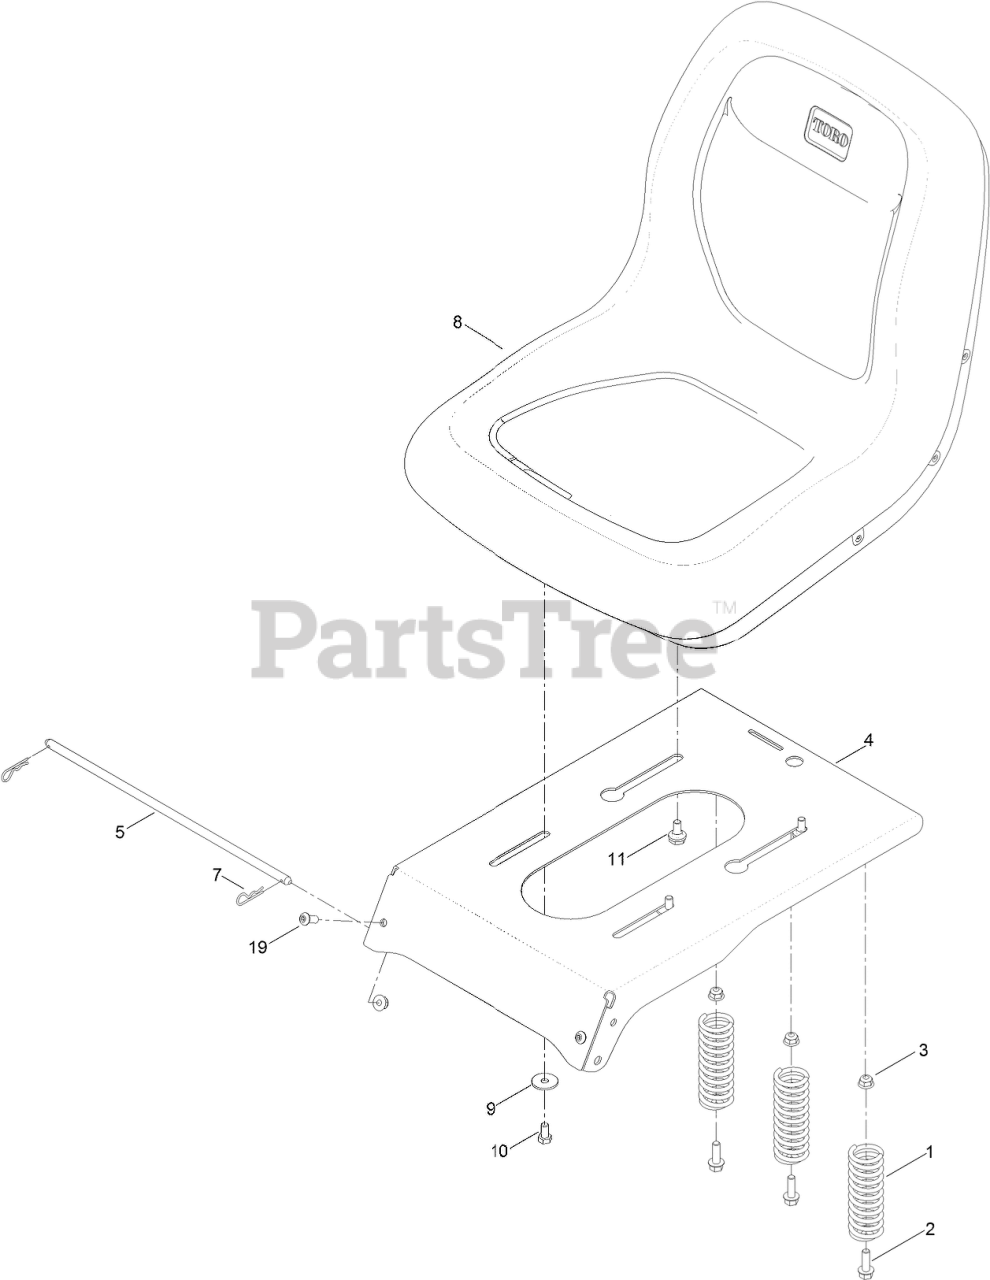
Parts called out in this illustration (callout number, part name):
1	SPRING-COMPRESSION
2	SCREW-HHF
3	NUT-HF, NI
4	PAN-SEAT
5	ROD-PIVOT, NARROW
7	PIN-COTTER
8	SEAT-18 INCH
9	WASHER-PIVOT
10	SCREW-HH
11	BOLT-SHOULDER,HFH
19	SCREW-HSBH
